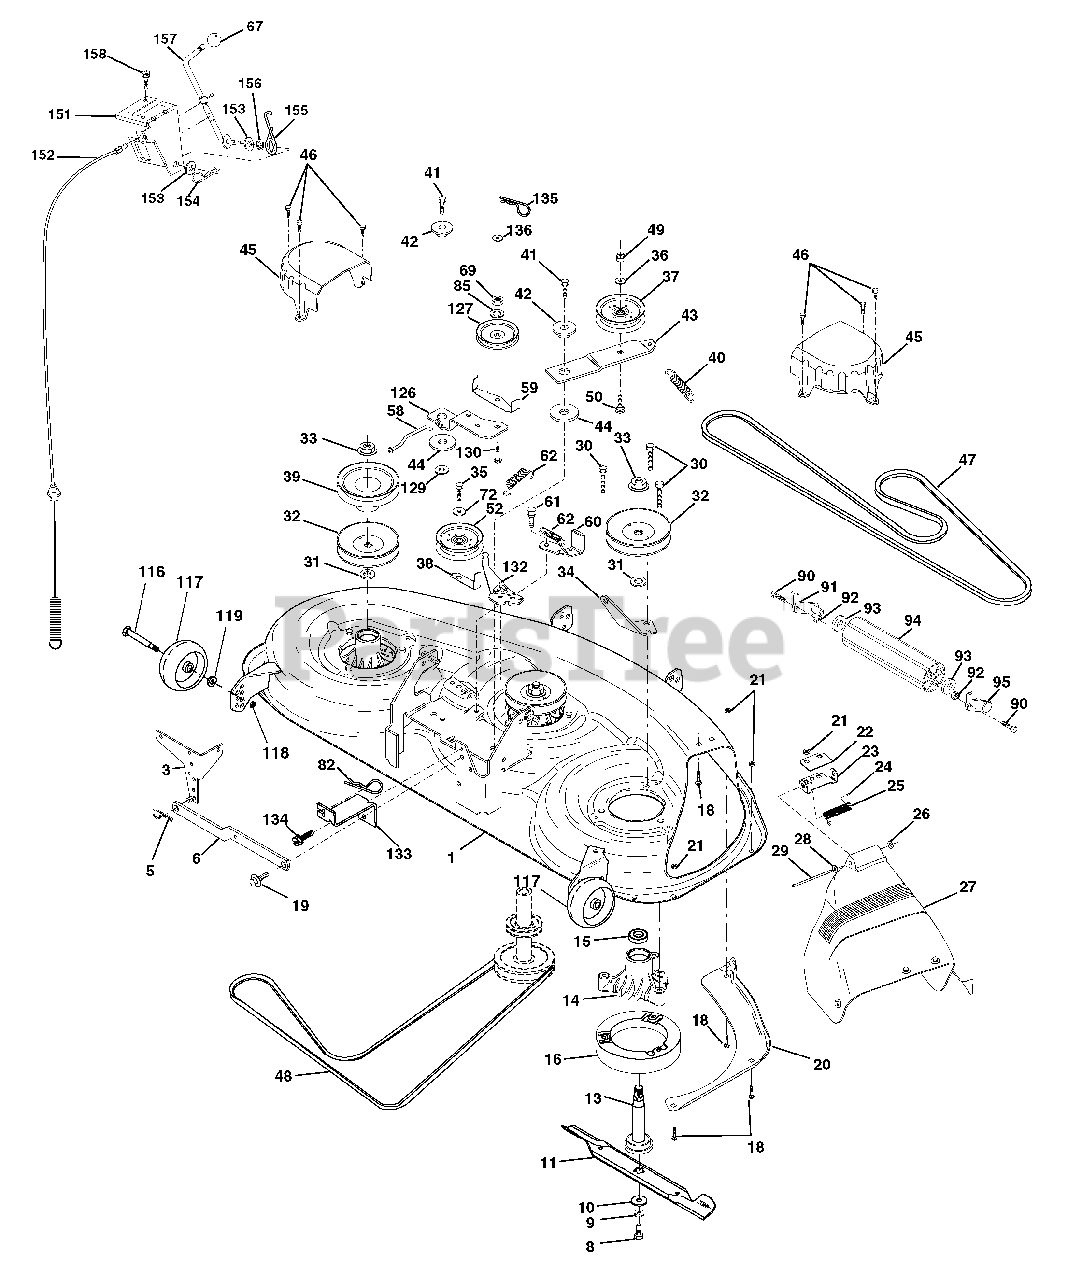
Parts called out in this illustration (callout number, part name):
1	Deck Asm., Mower 46"
3	Bracket Asm., Sway Bar
5	Retainer Spring
6	Arm, Suspension, Rear (Sway Bar)
8	Bolt, Patched 3/8-24 x 1-1/4 Gr. 8
9	Washer, Lock Hvy., Unplated 3/8
10	Washer, Hard Blade, Mower Vented
11	Blade Hi-Perf 46"
13	Shaft Asm. w/Lower Bearing
14	Housing, Mandrel
15	Bearing, Ball, Mandrel
16	Stripper, Mower Round
18	Bolt, Carriage 5/16-18 x 5/8
19	Bolt, Hex Head, Shoulder 5/16-18
20	Baffle, Vortex Mower 46"
21	Nut, Crownlock 5/16-18 UNC
22	Stiffiner, Bracket
23	Bracket, Deflector
24	Cap, Sleeve
25	Spring, Torsion, Deflector
26	Nut, Push
27	Shield, Deflector Mower
28	Washer 11/32 x 5/8 x 16 Ga.
29	Rod, Hinge
30	Screw, Thdroll Washer Head
31	Washer, Spacer Mower Vented
32	Pulley, Mandrel
33	Nut, Flg. Top Lock Cntr. 9/16
34	Anchor, Spring Deck 46"
35	Screw, Thdroll 3/8-16 x 1-3/4 Tytt
36	Washer 13/32 x 1 x 16 Ga.
37	Pulley, Idler, Flat
38	Keeper, Belt, Idler
39	Pulley, Idler, Driven
40	Spring, Secondary 44/46/50 Vent
41	Screw 3/8-16 x 1-1/4
42	Spacer, Retainer
43	Arm, Idler Secondary
44	Washer, Hardened
45	Cover, Mandrel Deck
46	Screw, Thdroll. 1/4-20 x 5/8
47	V-Belt, Mower, Secondary
48	V-Belt, Mower, Primary
49	Nut, Crownlock 3/8-16 UNC
50	Bolt, Carriage 3/8-16 x 1-1/2 Gr. 5
52	Pulley Idler
58	Rod Brake 46"
59	Guide Bolt 46" Mower Dr
60	Arm Asm Brake 46"
61	Bolt Shld 5/16-18
62	Spring Return
67	Knob Rd 3/8-16 Plstc Thds Blk
69	Nut Hex Jam 3/8-16 Unc
72	Washer 13/32 x 1 x 16 Ga.
82	Retainer Spring
85	Washer Lock 3/8
90	Bolt Fin Hex 5/16-18 x 1
91	Bracket Asm. Noseroller Lh
92	Nut Lock Hex 5/16-18
93	Washer 17/32 x 7/8 x 16 Ga.
94	Roller Nose
95	Bracket Asm. Noseroller Rh
116	Bolt, Shoulder
117	Gauge Wheel
118	Nut, Centerlock 3/8-16 UNC
119	Washer 3/8 x 7/8 x 14 Ga.
126	Arm, Idler, Primary Deck 46"
127	Pulley, Idler, V-Groove Dim. 4.25
129	Washer 13/32 x 2-3/8 x 8 Ga
130	Bolt Carriage Idler
131	Spring Return Idler
132	Arm Spring Brake Mower
133	Bracket Anchor Cable 46"
134	Screw Thdrol5/16-18 x 3/4
135	Retainer Spring Yellow
136	Washer 9/32 x 3/4 x 16 Ga
151	Bracket Clutch Cable
152	Clutch Cable 38"/46"
153	Washer Flat 3/8" Type B
154	Spring Retainer
155	Spring Retension Q
156	SPacer Clutch Cable
157	Rod Clutch Cable 3/8"
158	Screw Hex Thd Cut 1/4-20 x 5/8
158	Mandrel Asm 44"/46"/50" Service
158	Deck Complete (Std. Deck-Order separately mulch plateand gauge wheel components Key Nos. 101-106 and 116-118)
